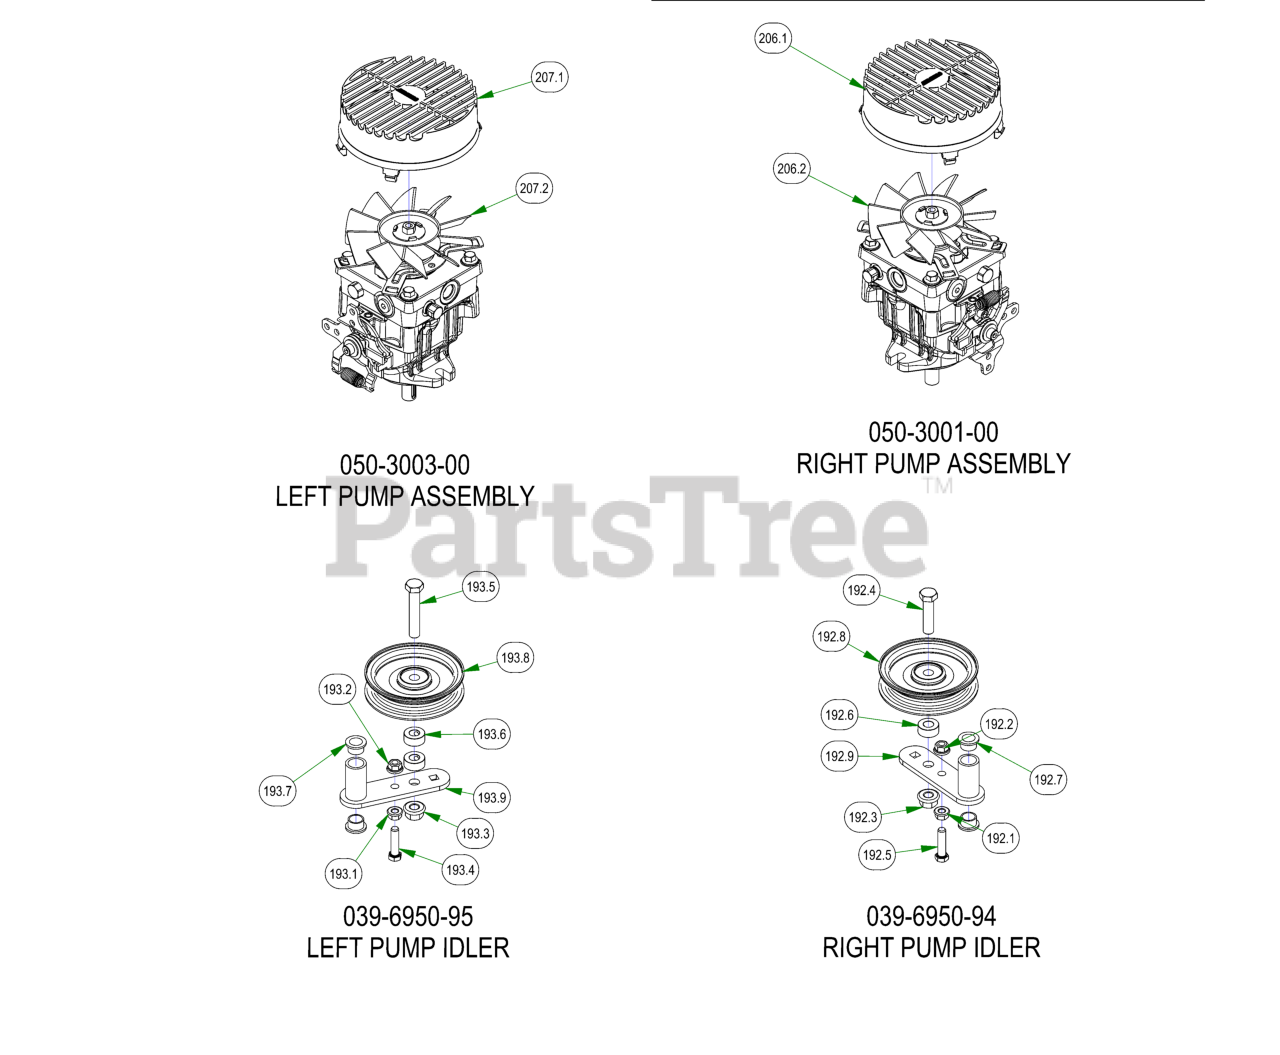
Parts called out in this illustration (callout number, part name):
44	5/16-18 X 2-1/4 HEX CAP SCREW (GR.5) ZINC
129	.380 ID X .625 OD X 1.500 LGTH 2019 OUTLAW BRAKE HANDLE
171.1	5" Pump Pulley
171.2	5/16-24 X 1/2 SOCKET SET SCREW KNURLED CUP POINT
192	2020 Diesel Pump Tensioner Assembly LH
192.1	3/8-16 HEX SERRATED FLANGE NUT HARD/ZINC
192.2	3/8-16 NYLON INSERT FLANGE LOCKNUT (GR.F) ZINC
192.3	1/2-13 NYLON INSERT FLANGE LOCKNUT ZINC
192.4	1/2-13 X 2 HEX CAP SCREW (GR.8) ZINC YELLOW
192.5	3/8-16 X 1-1/2 HEX CAP SCREW (GR.5) ZINC
192.6	1/2 SOLID SHAFT COLLAR (W/1 SET SCREW) ZINC
192.7	.627 ID X .753 OD X .500 LGTH X 1.000 FLG OD X .094 FLG THICK
192.8	4 3/4" Idler Pulley
192.9	Renegade - Gas Pump Idler - Weldment
193	2020 Diesel Pump Tensioner Assembly RH
193.1	3/8-16 HEX SERRATED FLANGE NUT HARD/ZINC
193.2	3/8-16 NYLON INSERT FLANGE LOCKNUT (GR.F) ZINC
193.3	1/2-13 NYLON INSERT FLANGE LOCKNUT ZINC
193.4	3/8-16 X 1-1/2 HEX CAP SCREW (GR.5) ZINC
193.5	1/2-13 X 2-3/4 HEX CAP SCREW (GR.5) ZINC
193.6	1/2 SOLID SHAFT COLLAR (W/1 SET SCREW) ZINC
193.7	.627 ID X .753 OD X .500 LGTH X 1.000 FLG OD X .094 FLG THICK
193.8	4 3/4" Idler Pulley
193.9	Renegade - Gas Pump Idler - Weldment
206	2019 Rogue/Renegade Left Pump 16cc
206.1	Fan Guard 6" - Fits Wheel
206.2	Hydro Fan - Light/Pup/Outlaw XP
207	2019 Outlaw Renegade Right Pump 16cc
207.1	Fan Guard 6" - Fits Wheel
207.2	Hydro Fan - Light/Pup/Outlaw XP
